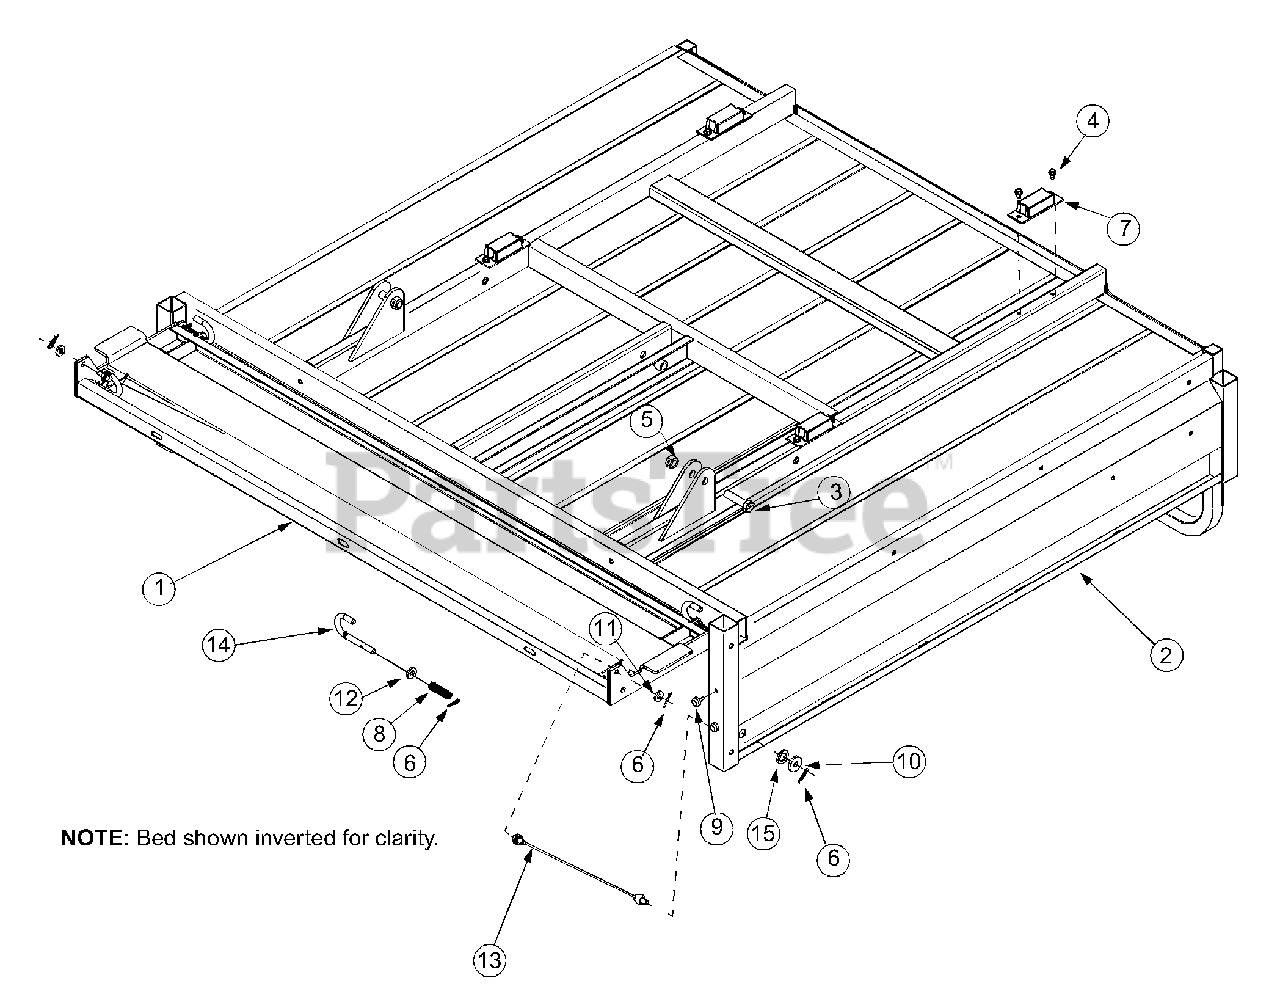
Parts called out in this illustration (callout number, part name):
1	Tailgate Assembly
2	Bed Assembly, Utility
3	Screw, Hex, 1/5-13 x 2.0, Gr5
4	Screw, Self-tapping, 1/4-20 x 0.500
5	Nut, Hex Lock, 1/2-13
6	Cotter Pin,.072 Dia x 1.13LG
7	Bumper, Extension Suspension
8	Compression Spring,.406 x.531 x 1.75 LG
9	Bumper,.62Dia x.3
10	Washer, Flat,.64 ID x 1.0 x.12
11	Washer, Flat,.344 x.750 x.120
12	Washer, Flat,.407 x.812 x.135 HDN
13	Cable, LIft 16.16 LG
14	Handle, Deck Release
15	Spacer, Shoulder.625 Dia x.324 Dia
